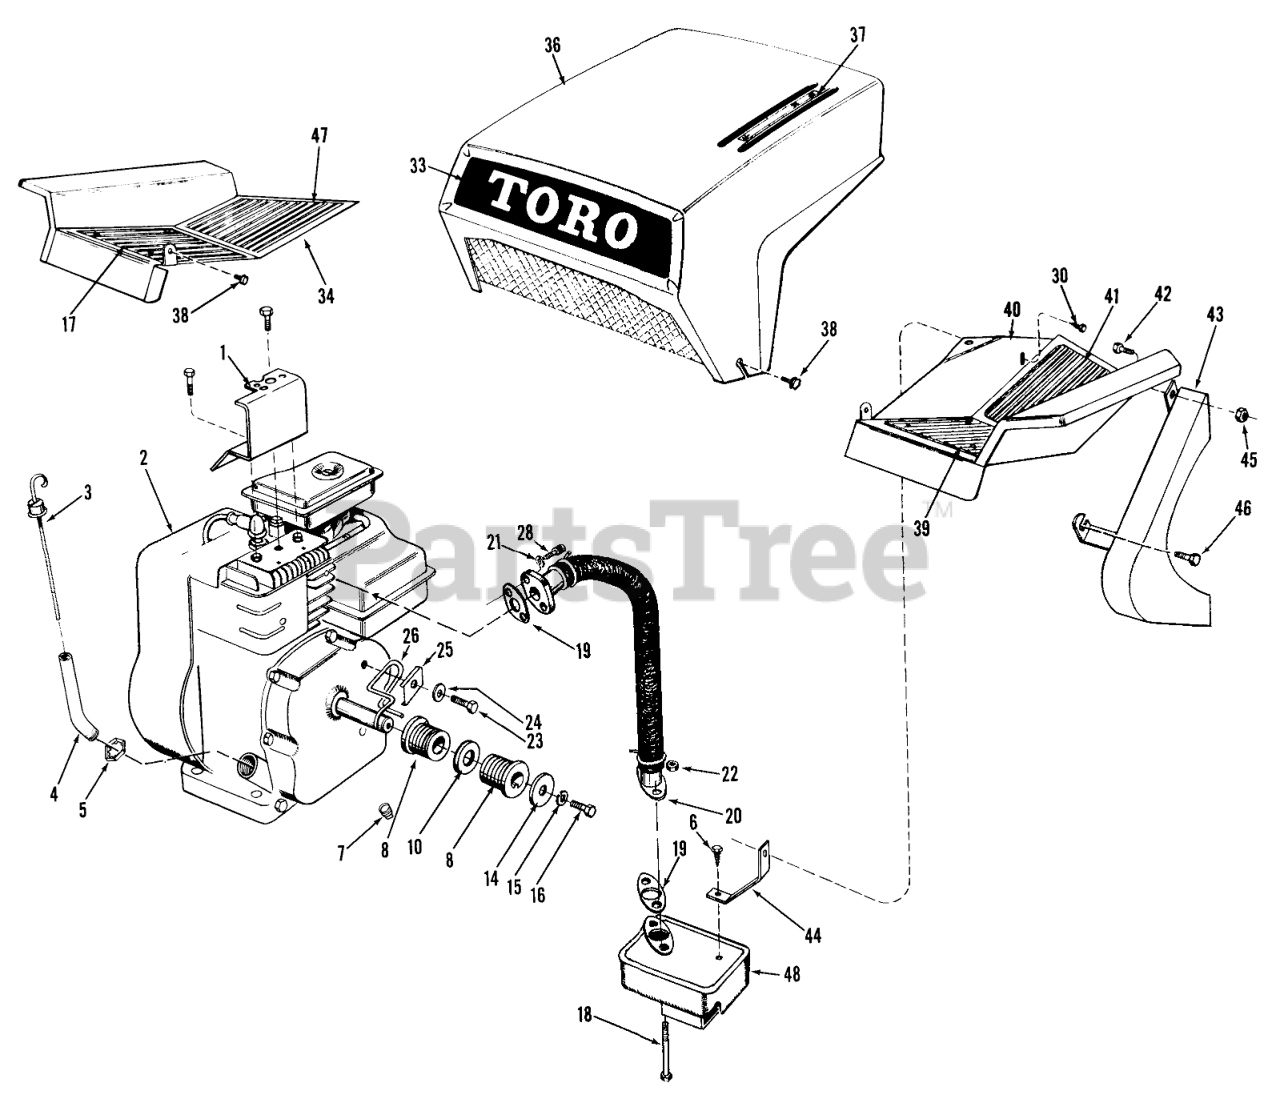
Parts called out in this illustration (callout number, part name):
2	Engine
5	Pal Nut
6	SCREW-HWHTF
7	PLUG-PIPE, SQH
10	WASHER-THRUST
15	WASHER-LOCK
16	SCREW-HH
18	Capscrew
21	WASHER-LOCK
22	NUT-KEPS
24	WASHER-FLAT
28	SCREW-HSH
30	10-16 X 3/8 THDG SCREW
46	SCREW-HH
48	Muffler
